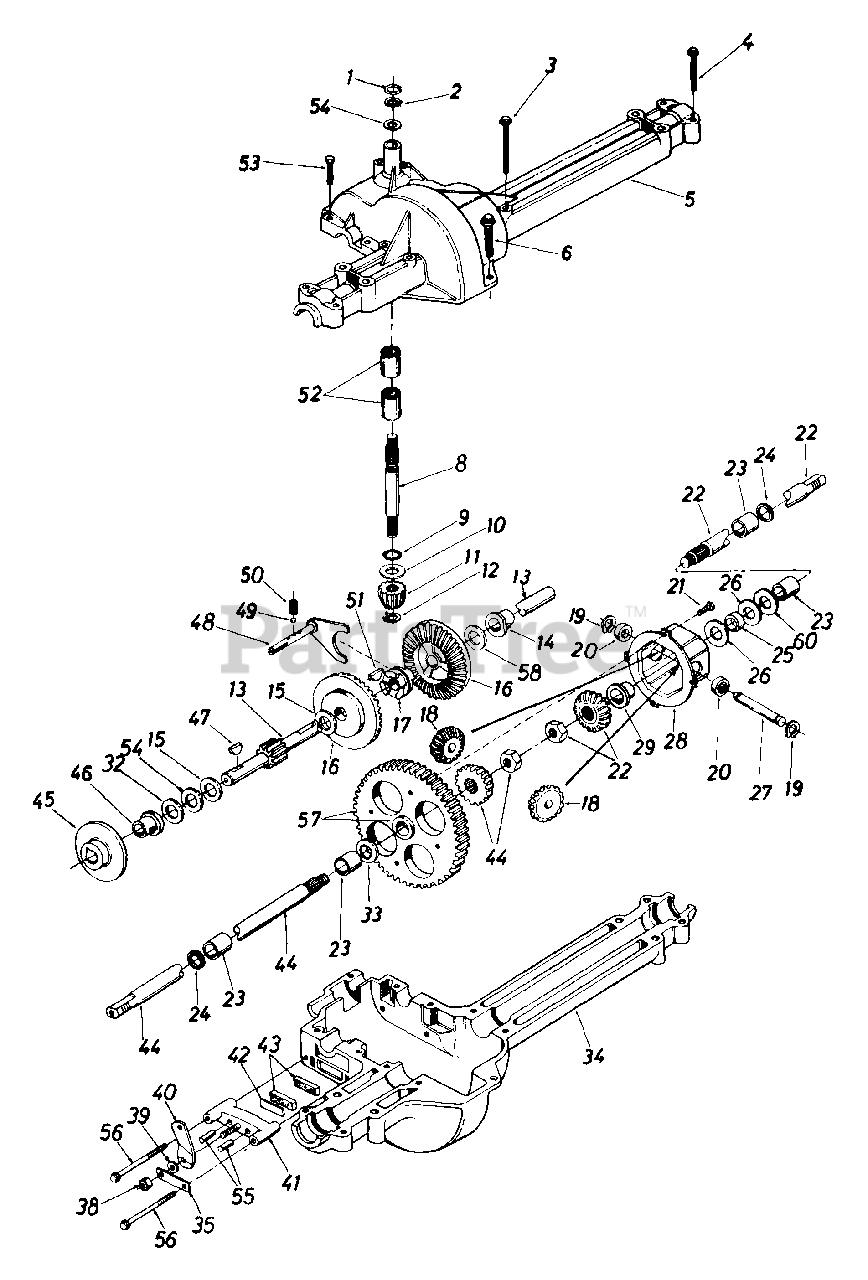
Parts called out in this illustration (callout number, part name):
1	Wire Ring
2	Retaining - Ring
3	Hex Wash. TT-Tap Scr. 1/4-20 x 1.75" Lg
4	Hex Tap Scr. 1/4-20 x 1.25" Lg.
5	Upper Housing
6	Hex TT-Tap Scr. 1/4-20 x .75" Lg.
8	Input Shaft
9	Square Seal 5/8" l.D.
10	Thrust Washer 5/8" I.D. x 1.25" O.D.
11	Pinion Input 14T
12	Retaining Ring
13	Drive Shaft
14	Flange Brg. 5/8" I.D. x 3/4" Lg.
15	Fl-Wash. 5/8" I.D. x 1.25"
16	Bevel Gear 42T
17	Clutch Collar
18	Miter Gear 15T (H.D.)
19	Snap Ring
20	Thrust Bearing
21	Pan Head Scr. 1/4-20 x .50" Lg. w/Patch
22	Axle R.H. Ass'y.
23	Sleeve Bearing 3/4" I.D. x 1.0" Lg.
24	Oil Seal 3/4" I.D.
25	Axle Spacer
26	Fl-Wash..760" I.D. x 1.5" O.D.
27	Cross Shaft
28	Differential Can Ass'y.
32	Washer (See Below)
33	Fl-Wash..760" I.D. x 1.5" O.D.
34	Lower Housing
35	Anti-Rotation Brkt.
38	Hex Nut 5/16-24 Thd.
39	Fl-Wash..344" I.D. x .875" O.D.
40	Actuating Arm
41	Brake Yoke
42	Puck Plate
43	Brake Puck
44	Axle L.H. Ass'y.
45	Brake Disc
46	Flange Bearing 5/8" I.D. x 15/16" Lg.
47	Woodruff Key 3/16 x 5/8 HT
48	Shift Fork Ass'y.
49	Ball Detent .250" Dia.
50	Spring Detent
51	#9 Hi-Pro Key 3/16" x 3/4" Dia. HT
52	Needle Brg. 5/8" I.D. x 1/2" Lg.
53	Hex Wash. TT-Tap Scr. 1/4-20 x 1.00" Lg.
54	Fl-Wash. 5/8" I.D. x 1" O.D. x .020 Thk.
55	Actuating Pin 5/16" Dia.
56	Hex Wash Hd. Self-Tap Scr. 1/4-20 Thd.
57	Differential Gear 72T Ass'y. w/Bearing
58	Fl-Wash. 5/8" I.D. x 1" O.D. x .020 Thk.
60	Washer (See Below)
